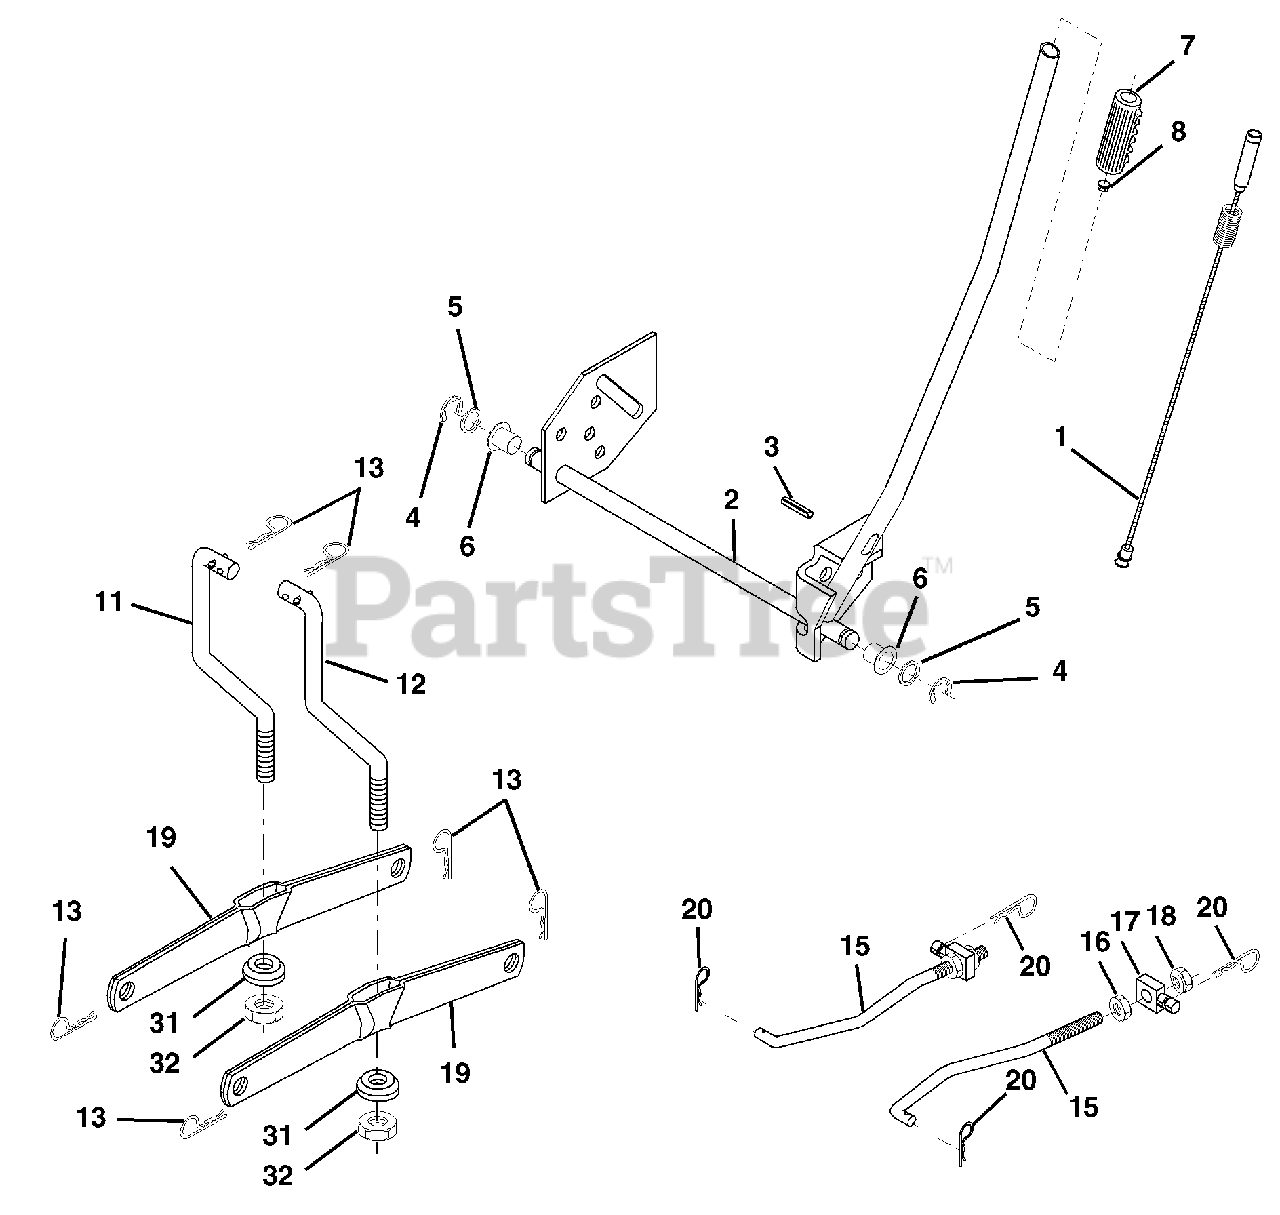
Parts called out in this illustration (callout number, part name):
1	Wire Asm Inner/Sprg w/plunger
2	Shaft Asm Lift RH
3	Pin Groove 1 500 Zinc
4	E Ring #5133-62
5	Washer 21/32 X 1 X 21 Ga
6	Bearing Nylon Blk 629 Id
7	Grip Handle Bicycle Matte Blk
8	Button Plunger Black
11	Link Lift LH Fixed Length
12	Link Lift RH Fixed Length
13	Retainer Spring
15	Link Front
16	Nut Jam Hex 1/2-13 Unc
17	Trunnion
18	Nut Lockw/Wsh 1/2-13 Unc
19	Arm Suspension Rear
20	Retainer, Spring
31	Bearing Pvt Lift
32	Nut Crownlock 3/8-24
